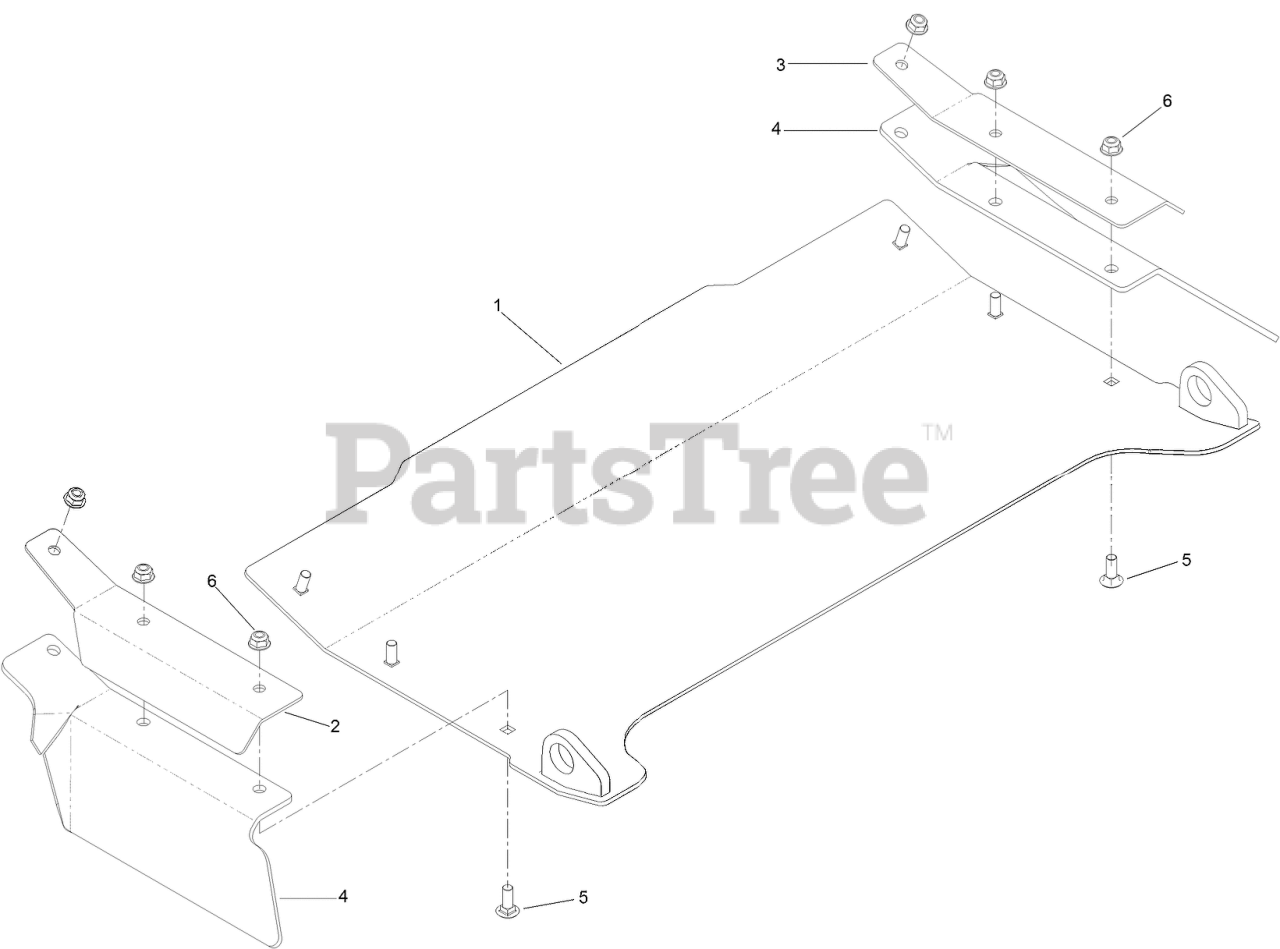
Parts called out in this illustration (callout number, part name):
1	DISCHARGE TUNNEL ASM
2	BRACKET-FLAP, LH
3	BRACKET-FLAP, RH
4	FLAP-RUBBER
5	SCREW-CARR
6	NUT-HF, NI
